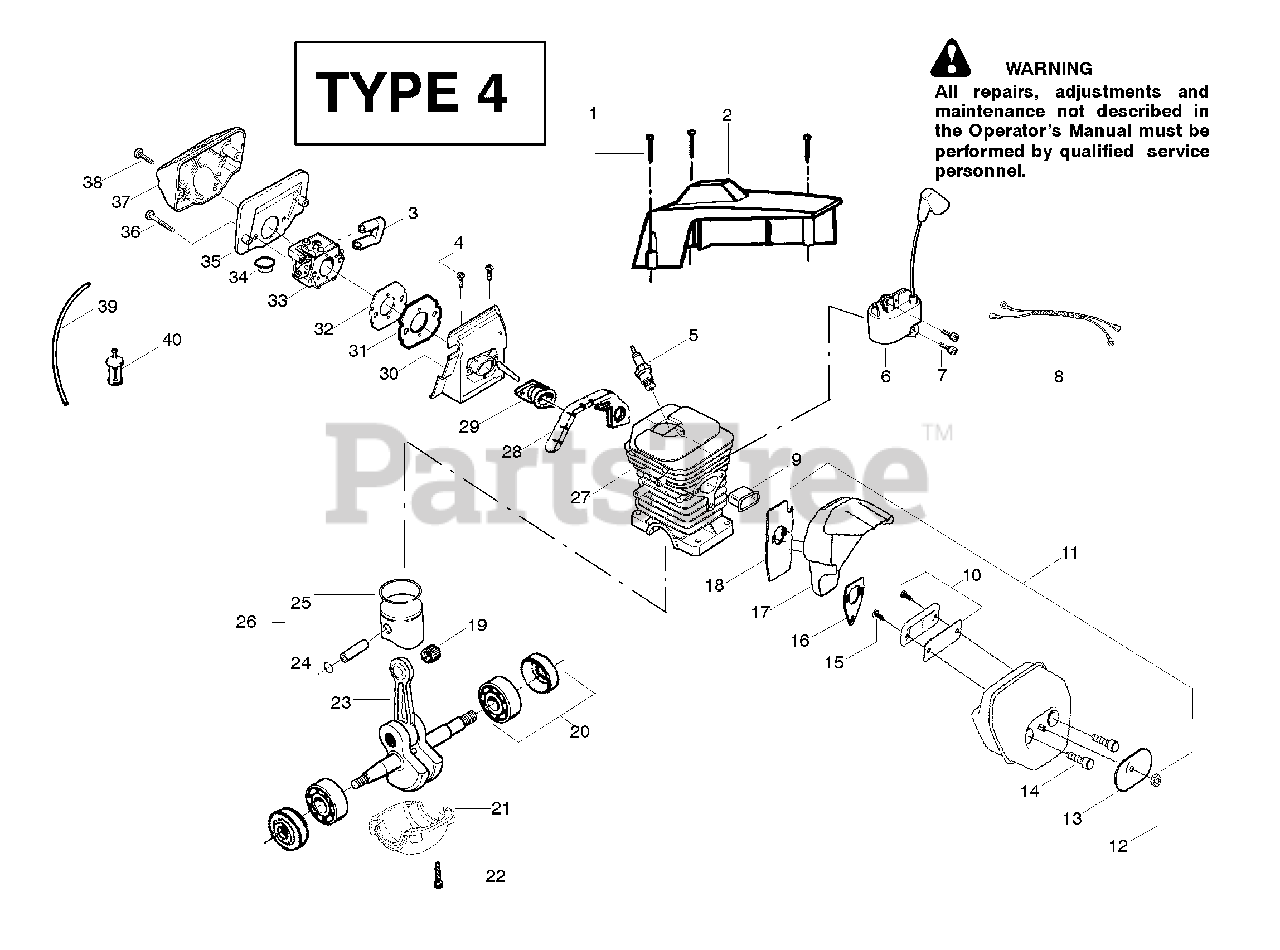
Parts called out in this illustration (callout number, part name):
2	Kit-Cylinder Shield
3	Grommet -Carb.
5	Spark Plug
6	Module-Ignition
8	Assy-Switch Wire
9	Insulator-Heat
10	Kit-Spark Arrestor
11	Kit-Muffler
12	Nut-Brass
13	Cover-Bolt
14	Bolt-Muffler
15	Screw-Spark Screen
16	Gasket-Muffler
17	Assy-Muffler Backplate
18	Backplate - Alum.
20	Assy-Bearing & Seal
21	Cap-Crankcase
23	Assy-C'shaft & Rod
24	Retainer-Piston Pin
25	Ring-Piston
26	Kit-Piston
27	Assy-Cyl/Crankcase
28	Seal-Super Clean
29	Intake Boot
30	Adapter-Carb.
31	Intake Plate-Carb
32	Gasket-Carb.
33	Kit-Carburetor
34	Isolator
35	Filter-Air
37	Filter-Air
39	Kit-Fuel Line
40	Assy-Fuel Pick-up
